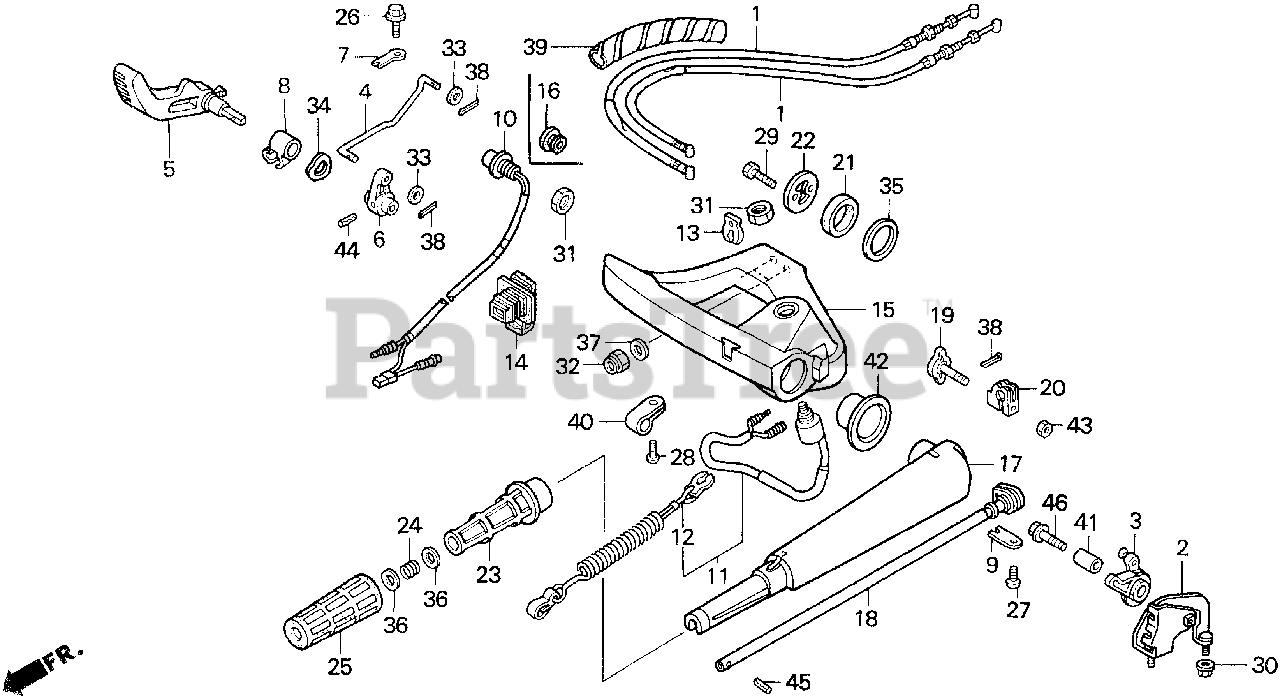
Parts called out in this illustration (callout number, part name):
1	CABLE SET, THROTTLE
1	CABLE, THROTTLE
2	BRACKET, THROTTLE CABLE
3	ARM, THROTTLE
5	LEVER, SHIFT
6	LINK A, SHIFT
7	PLATE A, SHIFT LINK
7	PLATE, SHIFT LINK A
8	COLLAR, DISTANCE
9	PLATE, SHIFT SHAFT
11	SWITCH ASSY., EMERGENCY STOP
12	WIRE, EMERGENCY
13	CLIP, EMERGENCY LOCK
14	GROMMET, CASE (LOWER) (A)
15	HANDLE, CARRYING *NH282MU* (OYSTER SILVER METALLIC-U)
16	GROMMET, CARRYING HANDLE
17	HANDLEBAR *NH282MU* (OYSTER SILVER METALLIC-U)
18	REEL, THROTTLE
19	BOLT, FRICTION
20	BLOCK, THROTTLE FRICTION
21	RUBBER, HANDLE MOUNTING
22	PLATE, HANDLEBAR
23	PIPE, GRIP
24	SPRING, GRIP PIPE
25	RUBBER, GRIP
26	BOLT, FLANGE (6X12)
27	SCREW, PAN (6X8)
28	SCREW, PAN (5X12)
29	BOLT, HEX. (6X16)
30	NUT, SELF-LOCK (6MM)
31	NUT, HEX. (16MM)
32	NUT, SELF-LOCK (10MM)
33	WASHER, PLAIN (5MM)
34	WASHER, WAVE (14MM)
35	WASHER, HANDLEBAR (36MM)
36	WASHER (10MM)
37	WASHER, PLAIN (10MM)
38	PIN, SPLIT (2.0)
39	TUBE, SPIRAL
40	CLIP, WIRE HARNESS
41	COLLAR, DISTANCE (6.5X10.5X16)
42	COLLAR, HANDLEBAR
43	NUT, HEX. (6MM)
44	PIN, SPRING (4X22)
45	PIN, SPRING (4X28)
46	BOLT, FLANGE (6X28)
